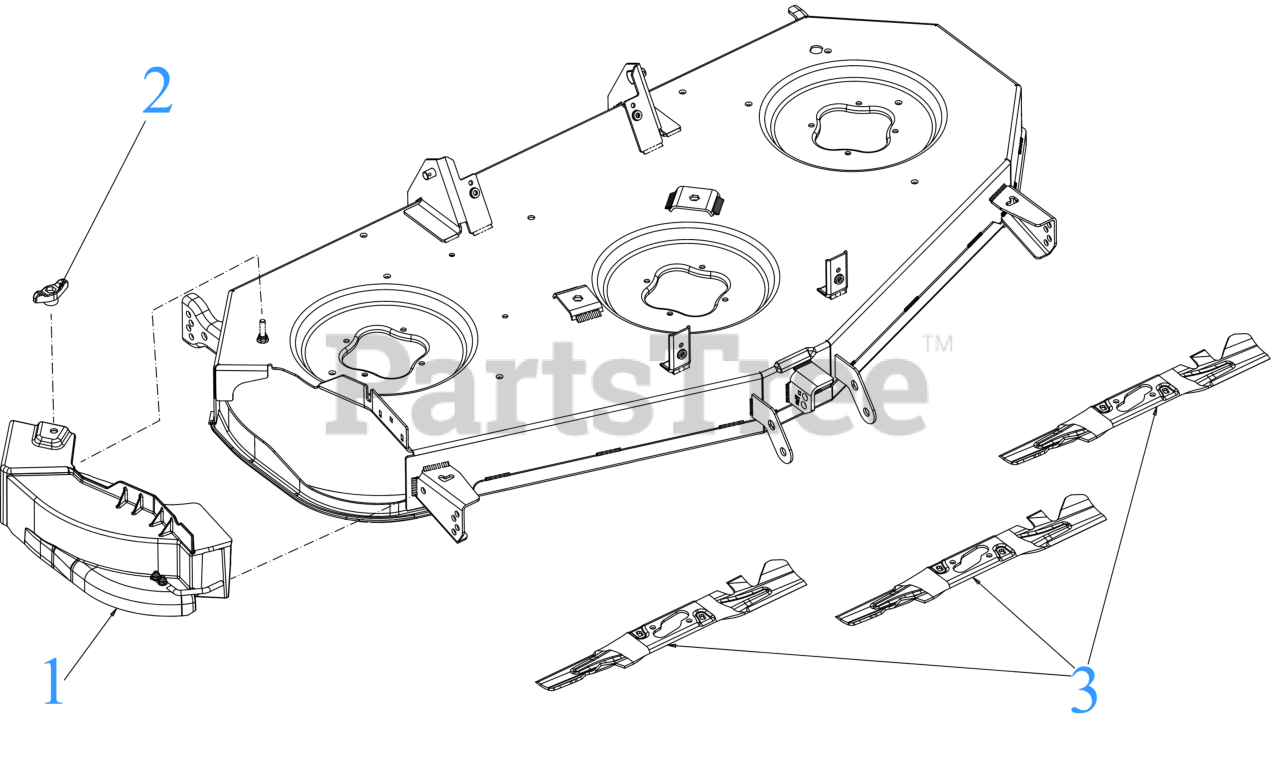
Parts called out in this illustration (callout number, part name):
1	MULCH PLUG
1	FLANGE LOCK NUT
1	MULCH PLUG MOUTING ROD
1	SCREW 1/4-20X.75 GR5
1	FLAT WASHER
2	WING KNOB 5/16-18
3	54" FASTATTACH XTREME MULCH BLADE
